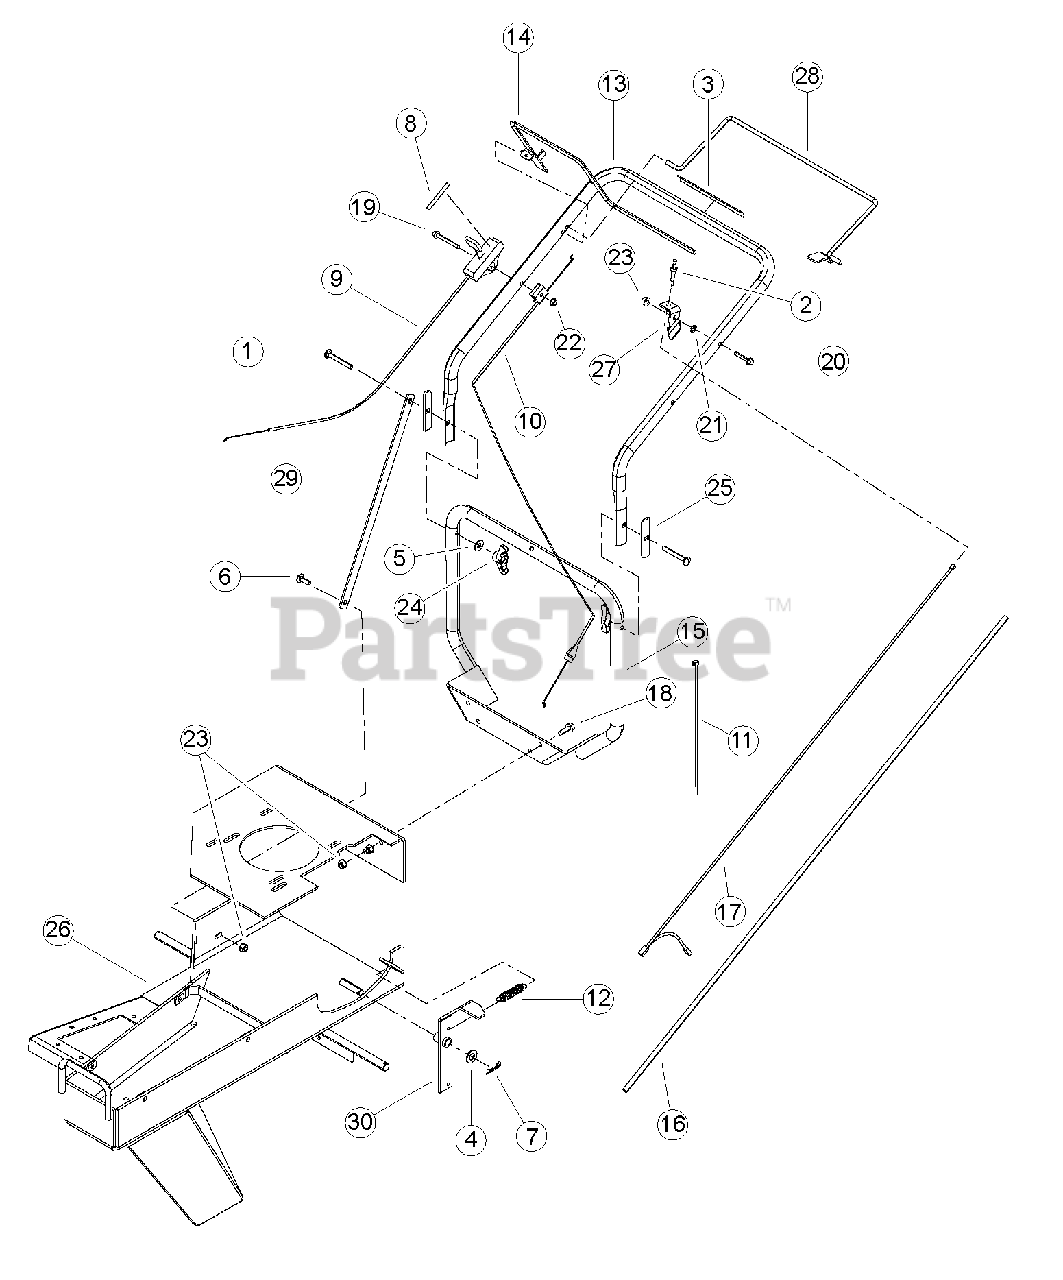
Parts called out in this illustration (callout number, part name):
1	BOLT, 5/16 X 2-1/2 CARRIAGE GR5 ZP
2	SWITCH, ENGINE KILL
3	DECAL, STUMPGRINDER CONTROL
4	WASHER 1/2 SAE FLAT ZP(56PC/LB
5	WASHER, 5/16 FLAT ZP
6	BOLT, 5/16 X 1 INCH GR5 CRG ZP
7	HAIRPIN CLIP ZP #203
8	DECAL, THROTTLE
9	THROTTLE CONTROL
10	CABLE, STUMP GRINDER
11	STRAP, 11 INCH BLACK TIE
12	SPRING,LT EXT .555OD X 2.75LG
13	UPPER HANDLE BAR
14	TOP BAIL WELDMENT
15	WELDMENT, HANDLEBAR
16	CONDUIT, 1/4 X 47 WIRE
17	WIRE ASSEMBLY, ENGINE KILL
18	BOLT, 5/16 X 1 FLANGE NC
19	BOLT, 5/16 X 1-3/4 FLANGE NC
20	BOLT, 1/4 X 1-1/2 FLANGE NC
21	WASHER, 5/16 EXTERNAL TOOTH ZP
22	NUT, 1/4-20 NYLOCK-FLANGE
23	NUT, 5/16-18 NYLOCK-FLANGE
24	KNOB, 5/16-18 UNC TEE W/LOCKING INSERT
25	BRACE, HANDLEBAR
26	WELDMENT, STUMPGRINDER FRAME
27	STRIP, SWITCH MOUNT
28	WELDMENT, BOTTOM BAIL
29	STRIP, HANDLEBAR SUPPORT
30	WELDMENT, WHEEL BRAKE
